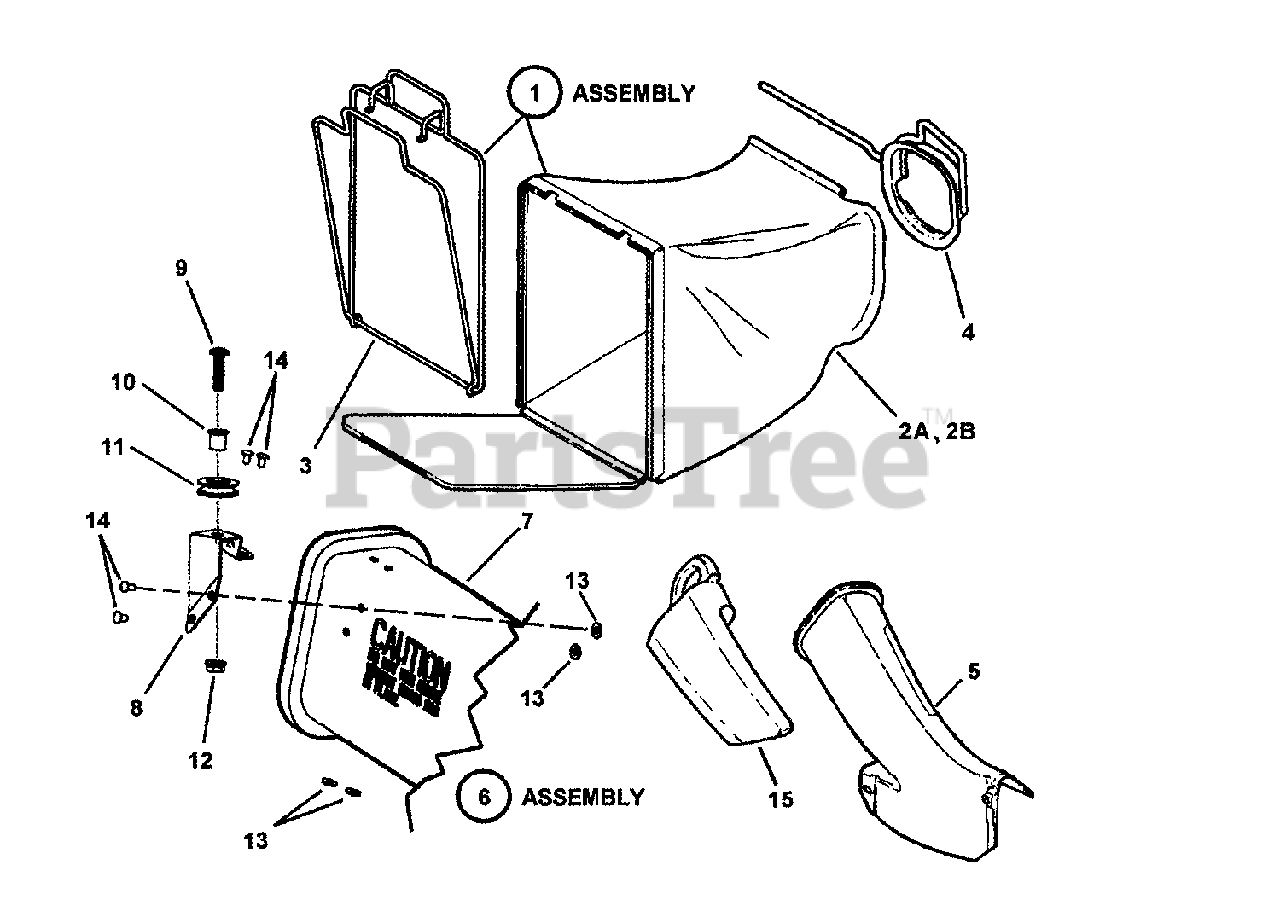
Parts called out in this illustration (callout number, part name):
1	ASSEMBLY, Grass Bag (Includes 2 thru 4)
2A	BAG, Door Type (Black w/Gold Letters) (12" Wide)
2B	BAG, Door Type (Black w/Gray Letters) (12" Wide)
3	ASSEMBLY, Bag Wire (12" Wide)
4	CONNECTOR, Grass Bag (weldment)
5	ADAPTER, Bag
6	ASSEMBLY, Grass Bag Adapter
7	ADAPTER, Bag
8	BRACKET, Rope Pulley
9	SCREW, 5/16-18 x 1-1/4" Pan Head Machine
10	BUSHING, Flange
11	PULLEY, Plastic
12	NUT, 5/16-18 Hex Flange Lock GR5
13	WASHER, 15/32" Flat
14	RIVET, 3/16 x .344
15	PLUG, Chute Adapter
